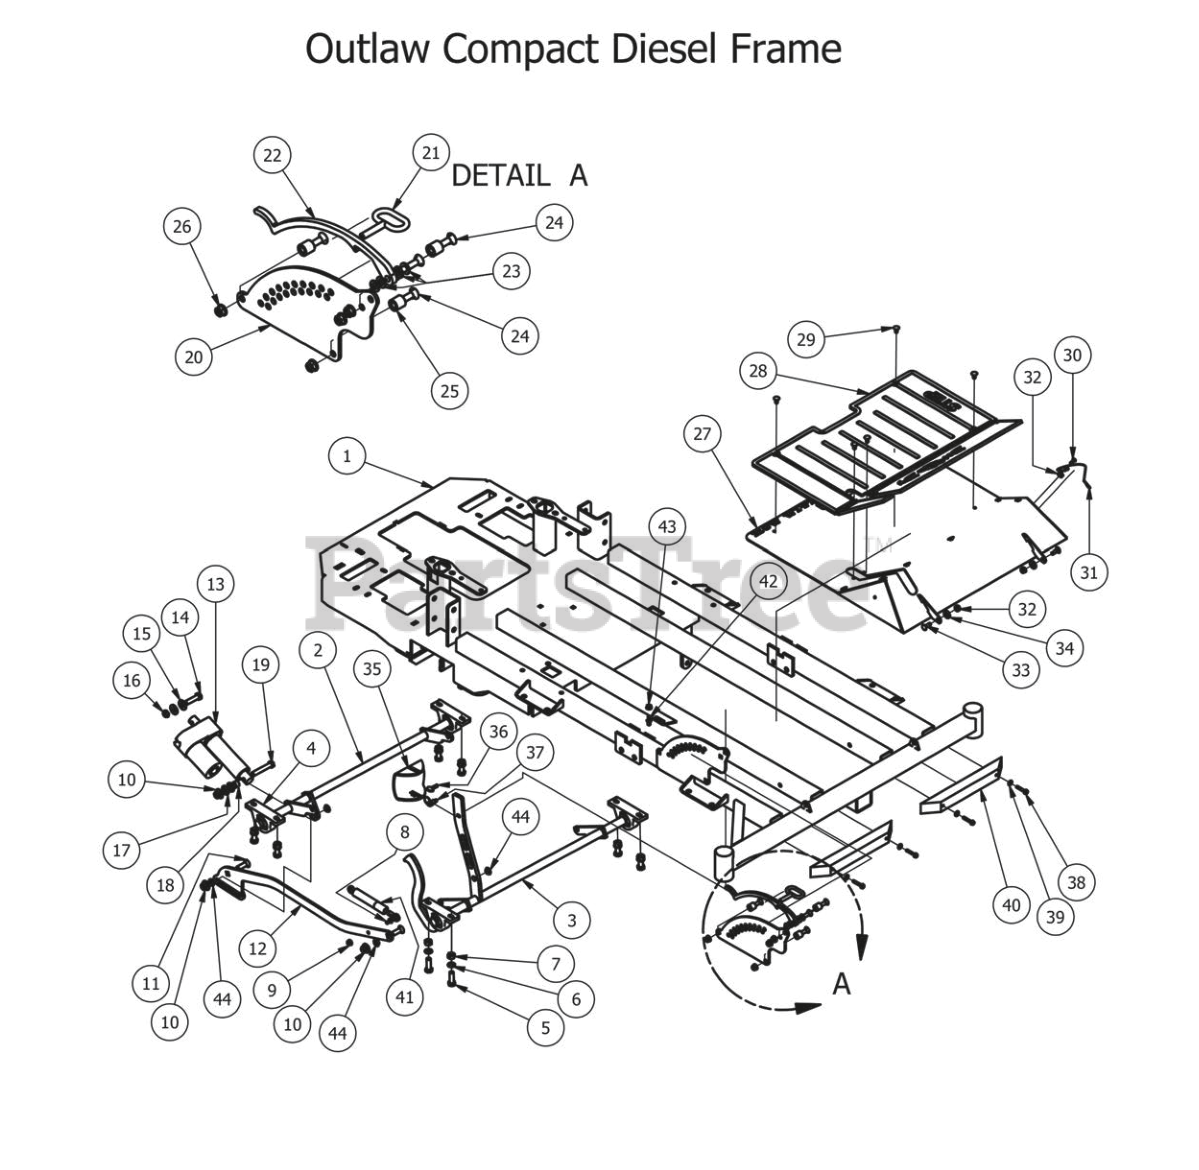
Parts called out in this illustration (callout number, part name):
1	Outlaw Diesel Frame 2012
2	Outlaw Actuator Bar (Rear)
3	Outlaw Front Actuator Bar Assembly
4	pillow block 2bolt sealmaster
5	1/2" x 1 1/2" Hex Bolt
6	1/2" Lock Washer
7	1/2" Hex Nut
8	10mm Damper Ball Stud-Steering
9	5/16" Flange Nut
10	1/2-13 Nylon Flange Nut-Orange
11	1/2 x 1-1/2 Carriage Bolt
12	Outlaw Susp Frame Linkage Bar
14	1/2-13x2 GR 5 Hex Bolt
15	1/2" Washer (Grade 8)
16	1/2" Nylcock Nut (1/2 Jam)
17	.635 ID Plastic Washer
18	1/2 x 1/2 Spacer
19	1/2-13 x GR 5 Hex Bolt Zinc
20	Outlaw Height Indicator Plate (Outer)
21	Deck height lever pin
22	Outlaw Deck Lever Lock
23	.390 x .750 x .062 Nylon Washer
24	3/8 x 1 3/4 Carriage Bolt
25	3/4 OD x 1/2 ID x 3\4 Length
26	3/8" Nylock Flange Nut
27	Outlaw Diesel Floor Panel
28	Foot Assist Floor Mat
29	Ratchet Fastener
30	1/4" x 5/8" BS C/S 18-8 SS
31	Floor board Cable W/ Swivel Ends
32	5/16-18 Nylon Flange Nut
33	5/16" x 1" Carriage Bolt
34	.360 ID Plastic Washer
35	Outlaw Deck Lift Pedal
36	5/16-18 x1 Thumb Screw Zinc
38	1/4" x 1 1/2" Self Tapping Screw
39	1/4" Flat Washer
40	14" Rubber Bumper
41	250lb Gas Spring -61" Deck
42	10mm Damper Ball Stud-Steering
43	5/16" Flange Nut
44	Actuator Bar Bushing-SF-1620-4
